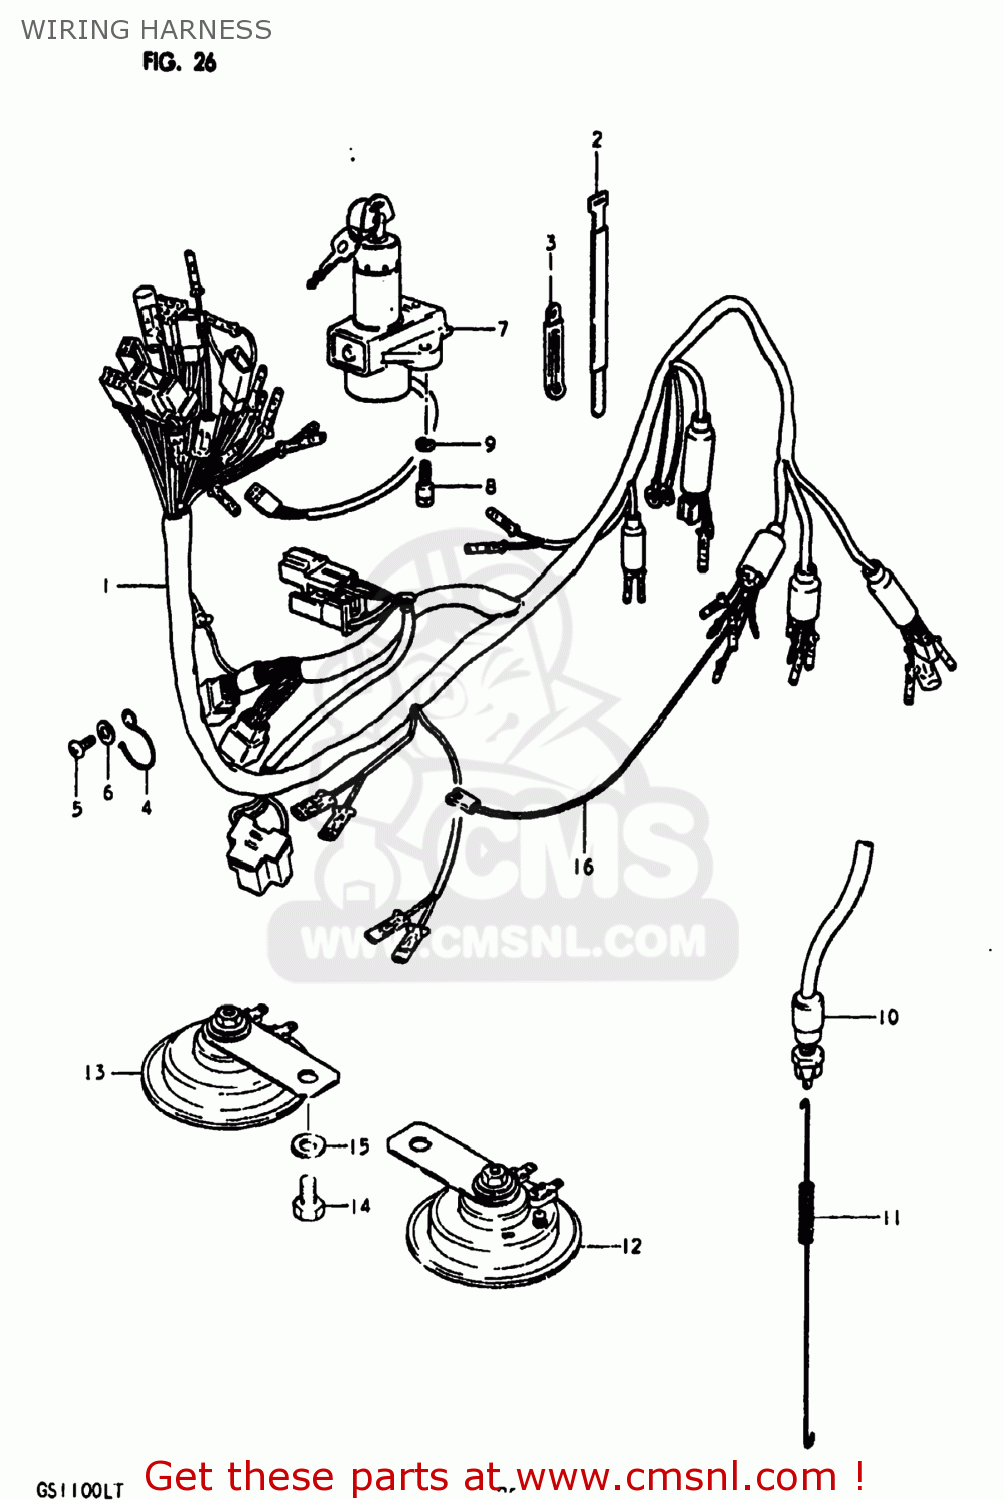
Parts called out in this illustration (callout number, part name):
1	HARNESS,WIRING
2	CLAMP
3	CLAMP
4	GUIDE,WIRING HARNESS
5	SCREW 6X12
6	WASHER
7	LOCK ASSEMBLY,STEERING
8	BOLT
9	LOCK WASHER
10	SWITCH ASSEMBLY,STOP LAMP
11	SPRING
12	HORN ASSEMBLY,LOW PITCH
13	HORN ASSEMBLY,HIGH PITCH
14	BOLT 8X12
15	WASHER
16	WIRE
